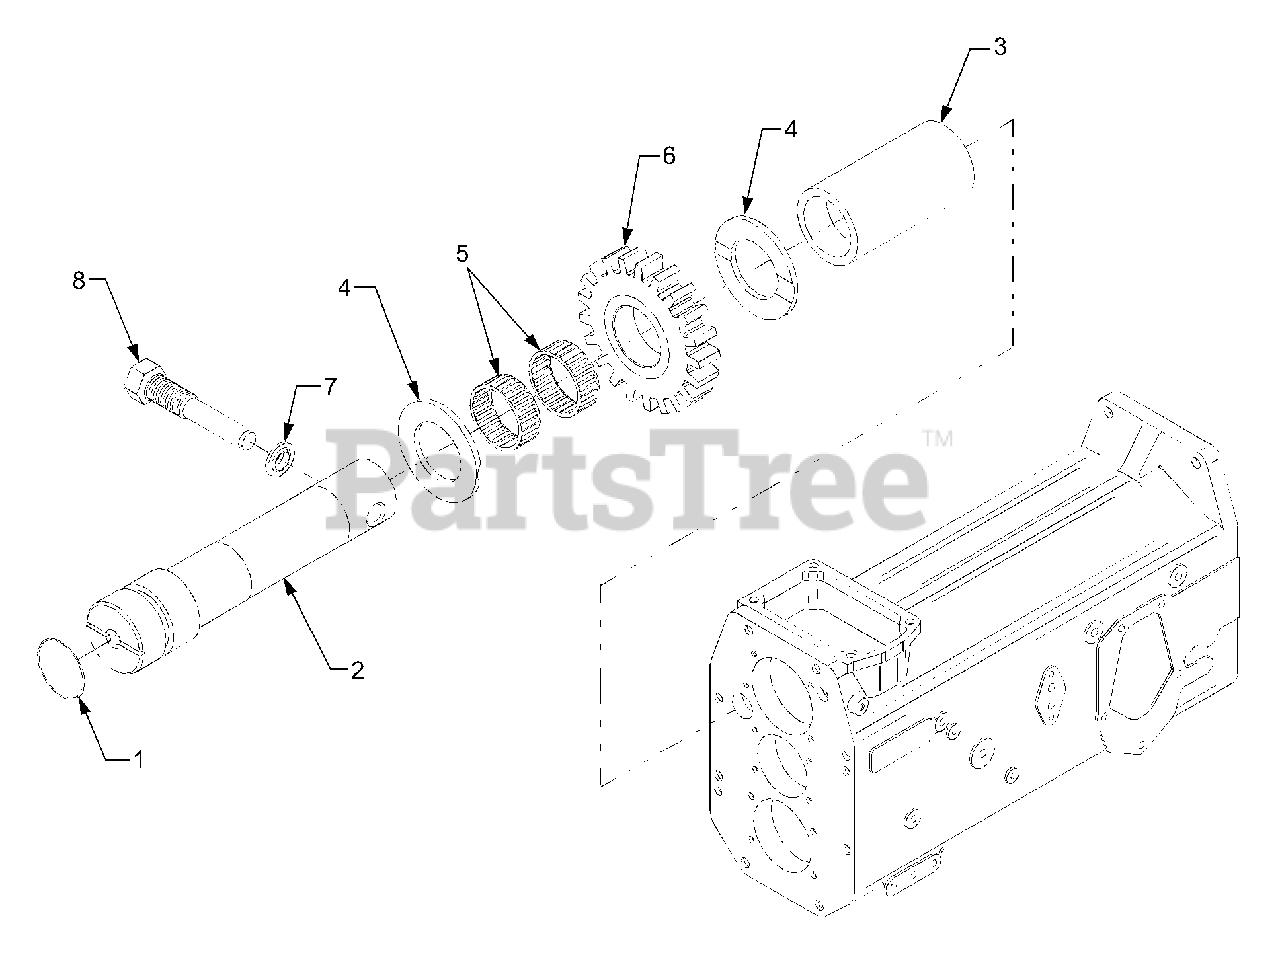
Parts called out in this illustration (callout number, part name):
2	Shaft, Reverse
4	Collar, Thrust
5	Bearing, Needle
